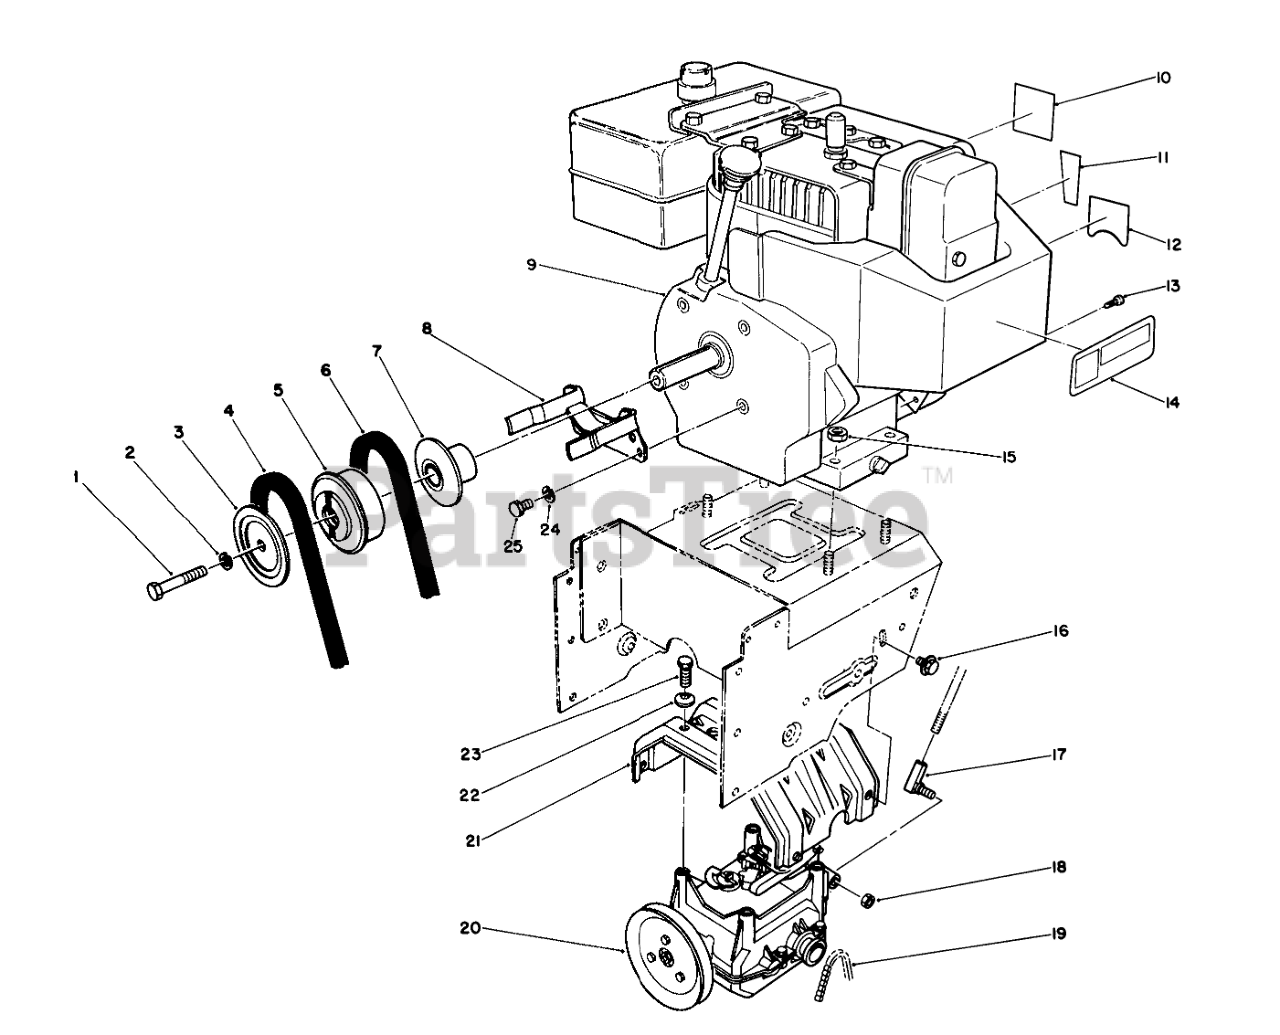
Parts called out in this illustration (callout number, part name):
1	SCREW-HH
2	WASHER-LOCK
3	SHEAVE-HALF, IMPELLER
4	V-BELT
5	PULLEY-ENGINE, CENTER
6	V-BELT-TRACTION
7	SHEAVE-HALF, TRACTION
8	Guide-Belt
10	DECAL-PRIMER
11	DECAL-THROTTLE
12	DECAL-CHOKE
13	SCREW-HWH
14	DECAL-HOT SURFACE, WARNING
15	NUT-HF
16	SCREW-HHF
17	JOINT-BALL
18	NUT-LOCK, NI
19	CHAIN
20	TRACTION GEARCASE ASM
21	Frame-Transmission
22	WASHER-SPRING
23	SCREW-HWHTF
24	WASHER-LOCK
25	SCREW-HH
